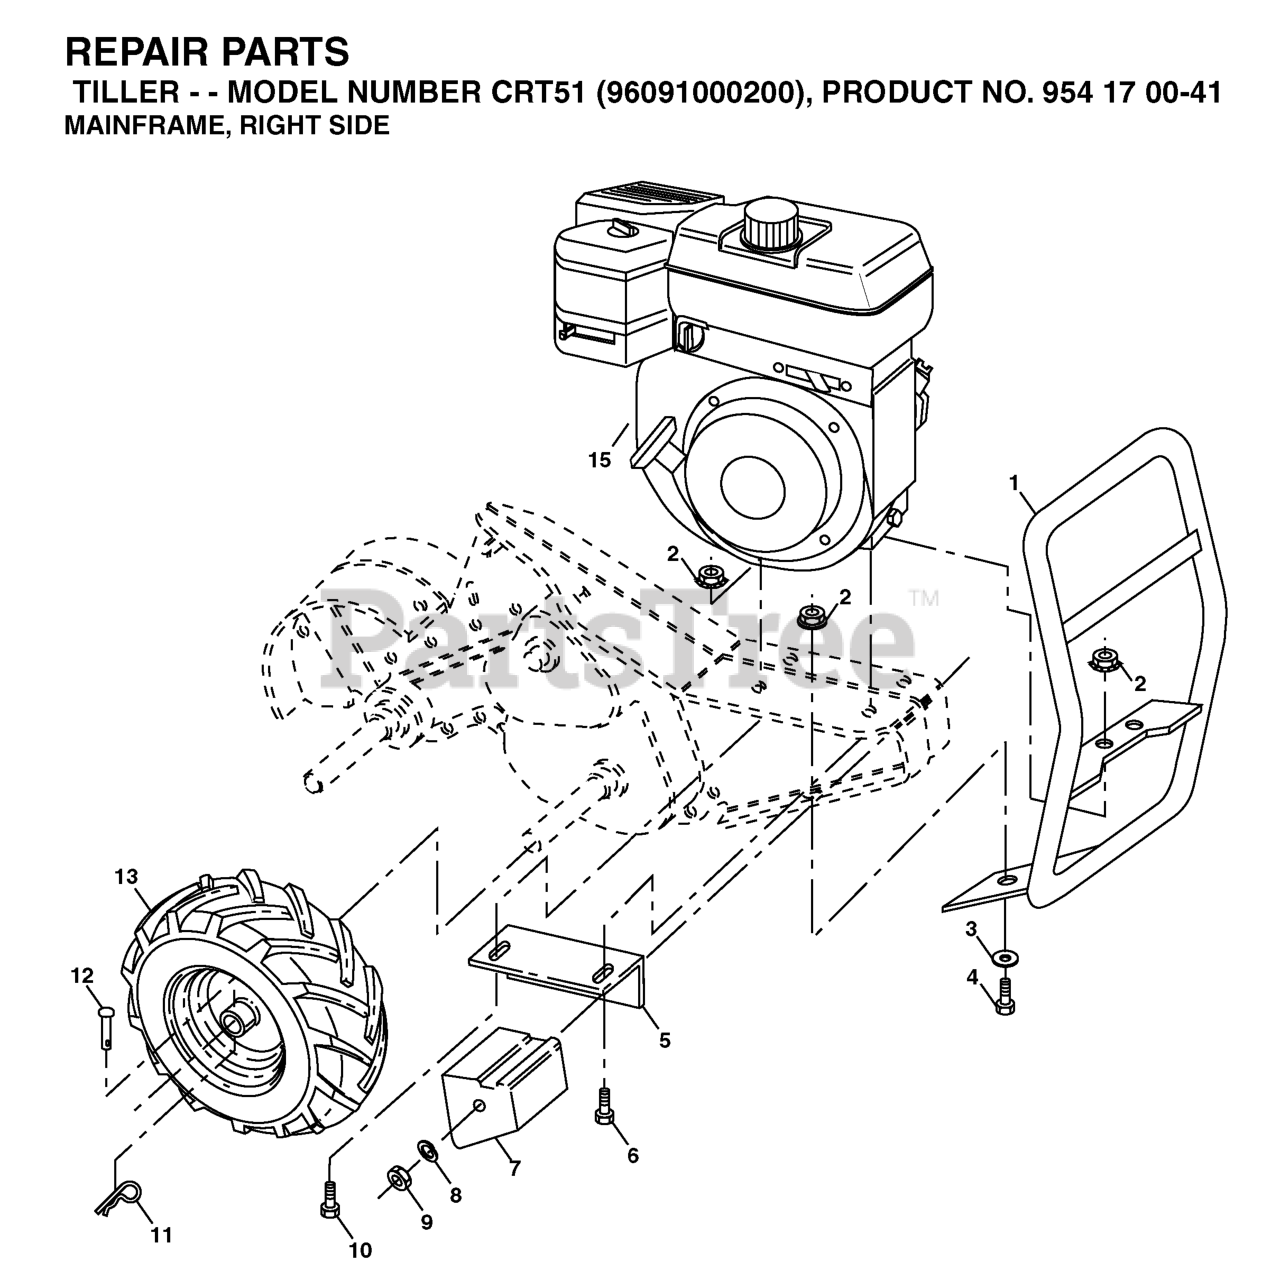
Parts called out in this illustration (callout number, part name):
1	RP.BUMPER.ASM.TILLER.
2	LOCKNUT-FLANGE 5/16-18
3	WASHER
4	BOLT
5	DNO BRACKET RH CRT
7	COUNTERWEIGHT, RH
8	WASHER, LOCK 3/8
9	NUT.HEX.3/8-16UNC
10	BOLT
11	RETAINER M
12	RIVET,DRILLED
13	TIRE.16X4-8.CHEVRON.TILLER
22	BOLT, HEX 5/16-18X1-3/4
